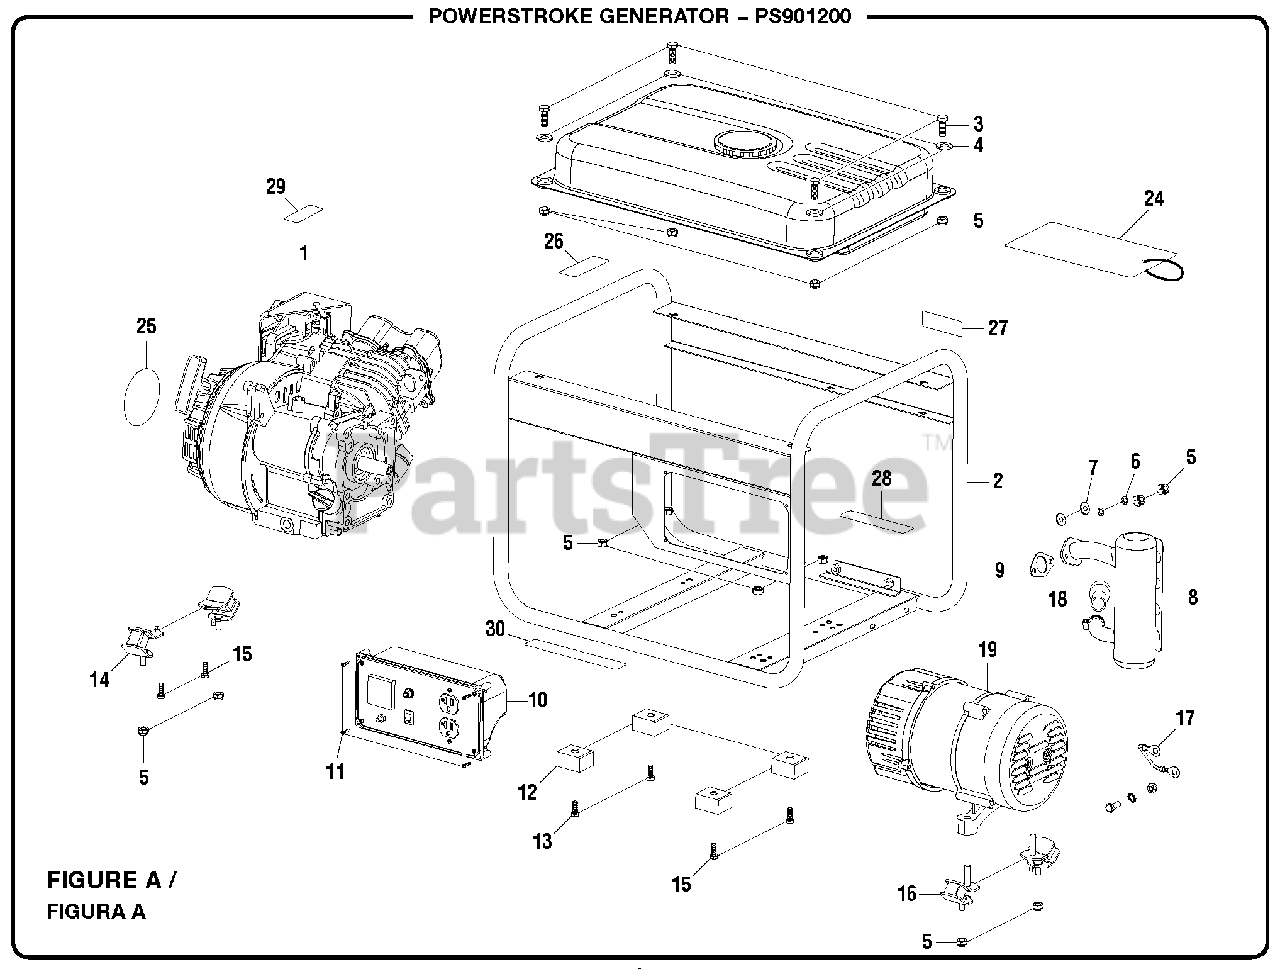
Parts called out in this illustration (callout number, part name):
2	Frame Assembly
3	Bolt (M8 x 20 mm, Flange Hd.)
4	Washer (M8)
5	Flange Nut (M8)
6	Spring Washer (M8)
7	Washer (M8)
8	Muffler Assembly
9	Muffler Gasket
10	Control Panel Assembly
11	Screw (ST4.2 x 12 mm)
12	Rubber Foot
13	Bolt (M8 x 35 mm, Flange Hd.)
14	Engine Isolator
15	Bolt (M8 x 16 mm, Flange Hd.)
16	Genhead Isolator
17	Ground Wire
18	Spark Arrester
19	Generator Head Assembly
20	Adaptor Housing
21	Bolt (M8 x 20 mm, Flange Hd.)
22	Spring Washer (M8)
23	Washer (M8)
24	Warning Hang Tag
25	Recoil Label
26	Fire Danger Label
27	Hot Surface Label
28	Fire Distance Label
29	Choke Label
30	Lubricant Label
